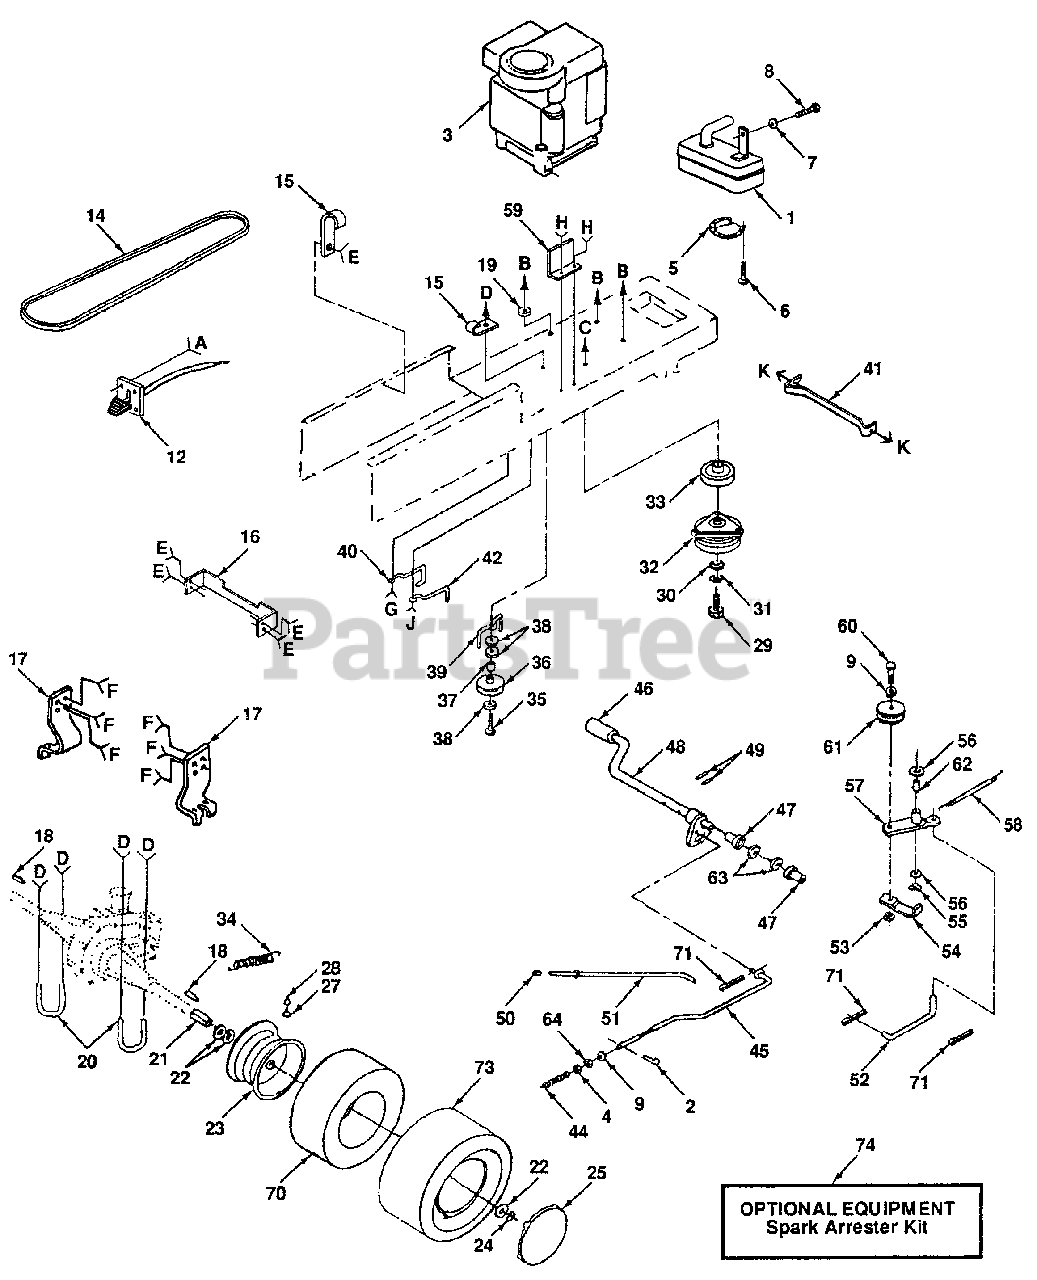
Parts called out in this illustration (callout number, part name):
1	Muffler
2	Clip, Hairpin
3	Engine, 14 H.P. Kawasaki
4	Nut, Jam, Hex 3/8 - 16 UNC
5	Deflector, Exhaust
6	Screw, Spider Lock #8 x 1 /2
7	Washer 9/32 x 1/2 x 16 Gauge
8	Bolt, Hex M6 x 1 x 12mm
9	Washer 13/32 x 13/16 x 16 Gauge
12	Control, Throttle/Choke
14	V-Belt, Drive
15	Clip, Insulated
16	Bracket, Mounting, Hydro T/A
17	Bracket, Transaxle
18	Key, Square 1 /4 x 2
19	Washer, Lock, Hvy. Helical Spring
20	U-Bolt 3/8 - 16 x 2.83
21	Spacer, Split
22	Washer 1-1/32 x 1-5/8 x 16 Gauge
23	Rim, Rear 8"
25	Cover, Wheel 8"
27	Stem, Valve
28	Cap, Valve
29	Bolt, Fin M10 x 1.5 x 100mm
30	Washer 15/32 ID x 1-1/2 OD x .250
31	Washer, Lock 7/16
32	Clutch, Electric
33	Pulley, Engine
34	Spring, Brake Return
35	Bolt, Hex 3/8 - 16 x 2-3/4
36	Idler, Flat
37	Spacer
38	Washer 13/32 x 13/16 x 12 Gauge
39	Retainer, Belt
40	Keeper, Belt, Engine, L.H.
41	Retainer, Clutch Assembly
42	Keeper, Belt, Engine, R.H.
44	Spring, Rod, Brake
45	Rod, Brake
46	Cover, Pedal
47	Bearing, Nylon
48	Shaft, Assembly, Foot Pedal
49	Pin, Roll 3/16 x 1
50	Cap, Plunger
51	Rod, Brake, Park
52	Link, Clutch
53	Nut, Crownlock 3/8 - 16
54	Retainer, Belt
56	Washer, Hardened
57	Arm Assembly, Idler
58	Spring, Return, Clutch
59	Bracket, Switch
60	Bolt, Hex 3/8 - 16 x 1-1/2
61	Pulley, Idler
63	Washer 21/32 x 1 x 16 Gauge
64	Locknut, Hex w/Washer Insert 3/8 - 16 UNC ZN
70	Tube
71	Pin, Cotter 1/8 x 3/4
73	Tire, Rear
74	Spark Arrester Kit
